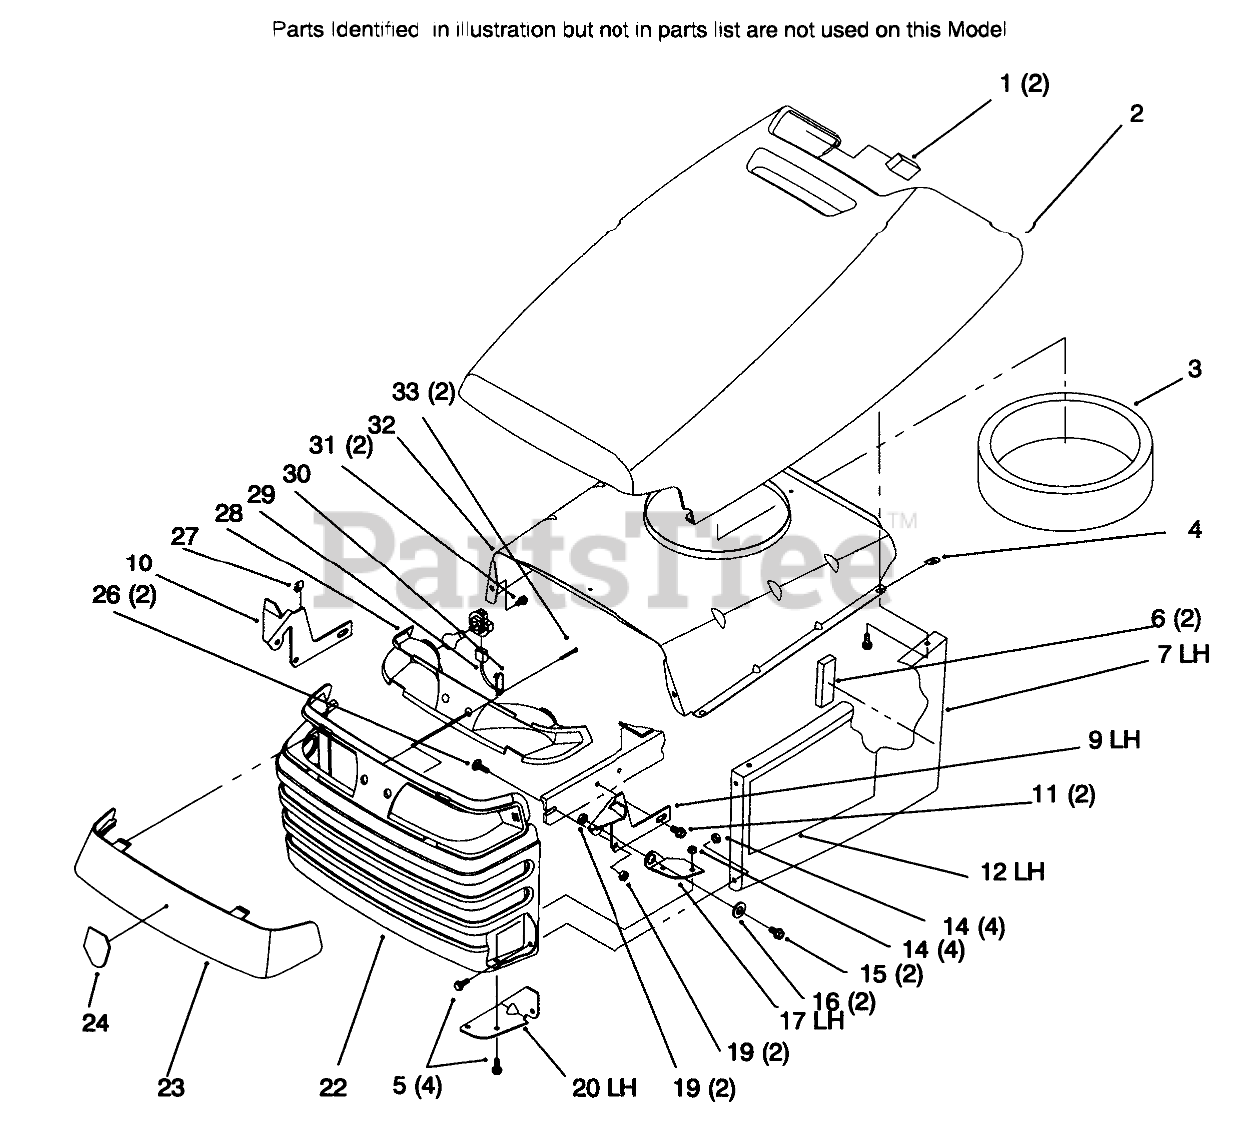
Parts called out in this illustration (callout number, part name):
1	FOAM-HOOD
2	HOOD ASM
3	SEAL-AIR INLET, TWIN
5	SCREW-HWH
6	FOAM-SIDEPANEL
7	HOOD-SIDE, LH
8	HOOD-SIDE, RH
9	BRACKET-HINGE, LH
10	BRACKET-HINGE, RH
11	SCREW-HWHTF
12	DECAL - LH HOOD
13	DECAL - RH HOOD
14	NUT-LOCK, HHF
15	SCREW-HH
16	BUSHING
17	HINGE-HOOD, LH
18	HINGE-HOOD, RH
19	NUT-LOCK, NI
20	BRACKET-HOOD HINGE, RH
21	BRACKET-HOOD HINGE, LH
22	Screen/Grill ASM
23	LENS - HEADLIGHT
24	EMBLEM-HORSEHEAD
26	BOLT-CARR
27	CLIP-RETAINER, WIRE
28	HEADLIGHT REFLECTOR ASM
29	HARNESS-WIRE, LIGHTS
30	TIE-CABLE
31	SCREW-PLASTITE
32	BAFFLE-HOOD, UPPER
